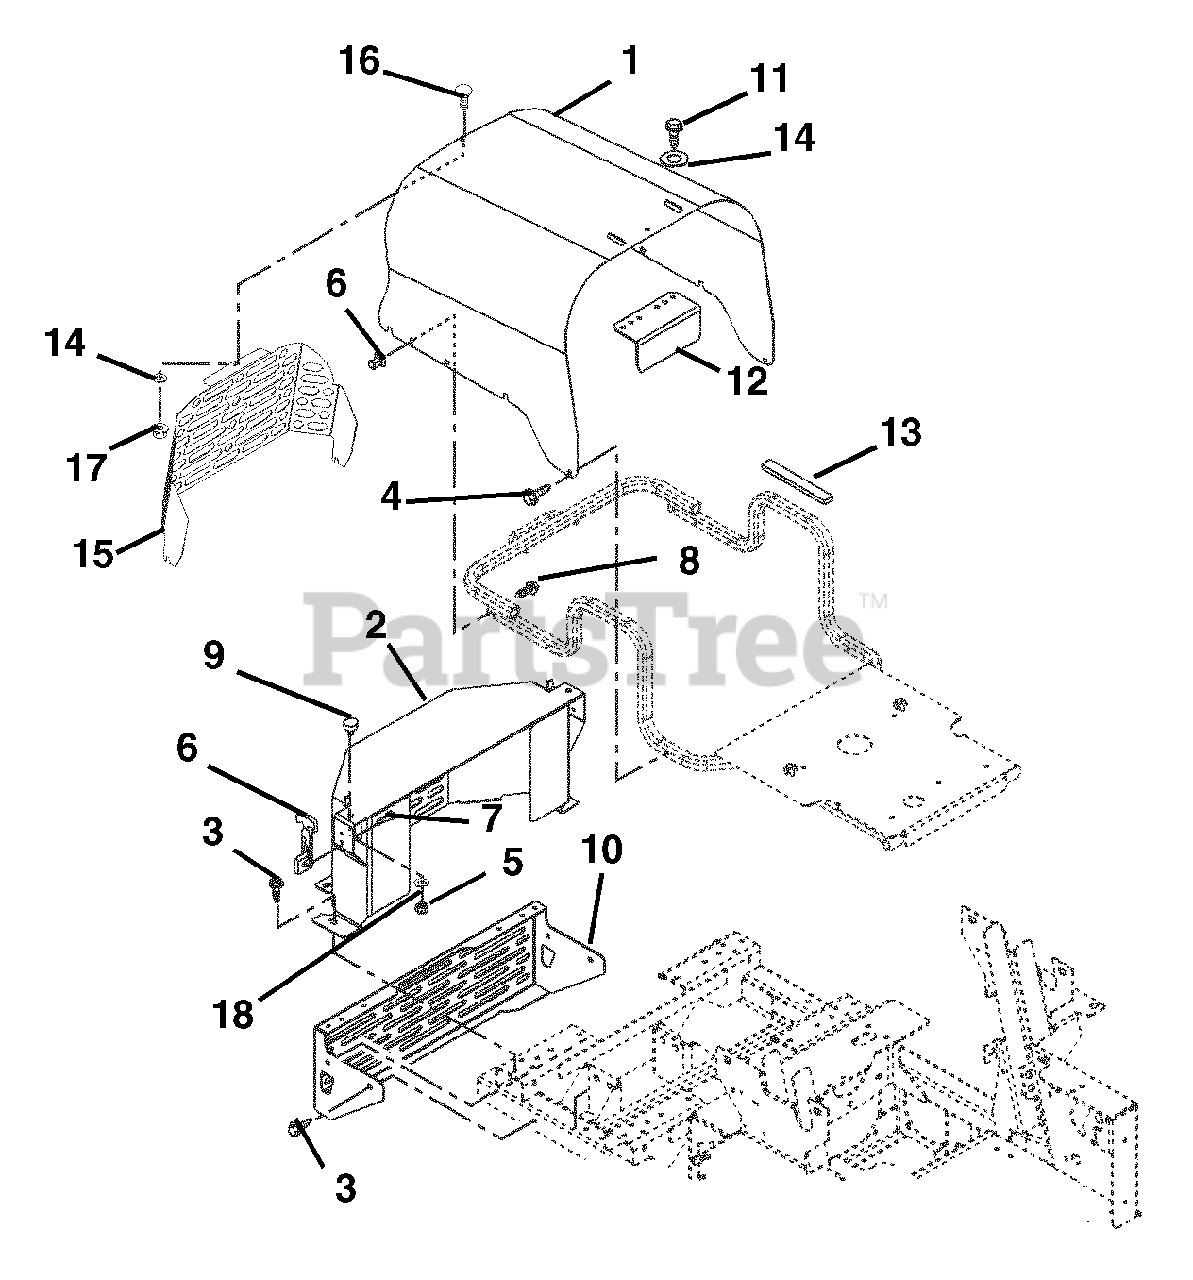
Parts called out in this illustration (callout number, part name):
2	Weldment, Belt Guard (036, 037)
2	Weldment, Belt Guard (038, 039, 309)
3	Screw-Tapping .38-16 x .75 Hex Washer Head
4	Screw-Tapping .38-16 x .50 Hex Washer Head
5	Nut-Hex .31-18
6	Latch-Rubber
7	Screw-Machine 10-24 x .50 Hex Washer Head
8	Screw-Machine 10-24 x 1.50 Hex Washer Head
9	Button, Bumper
10	Bumper-Rear
11	Screw-Tapping .25-20 x .50 Hex Washer Head
12	Guard, Radiator Cap (036, 037)
12	Guard, Radiator Cap (038, 039, 309)
13	VHB Tape
14	Washer-Flat-Steel .281 x .62 x .065
15	Guard, Hood
16	Bolt-Round Head Square Neck .25-20 x .50 Grade 5
17	Nut-Locking-Top-Flange .25-20
18	Washer-Locking .31 x .078 Regular
